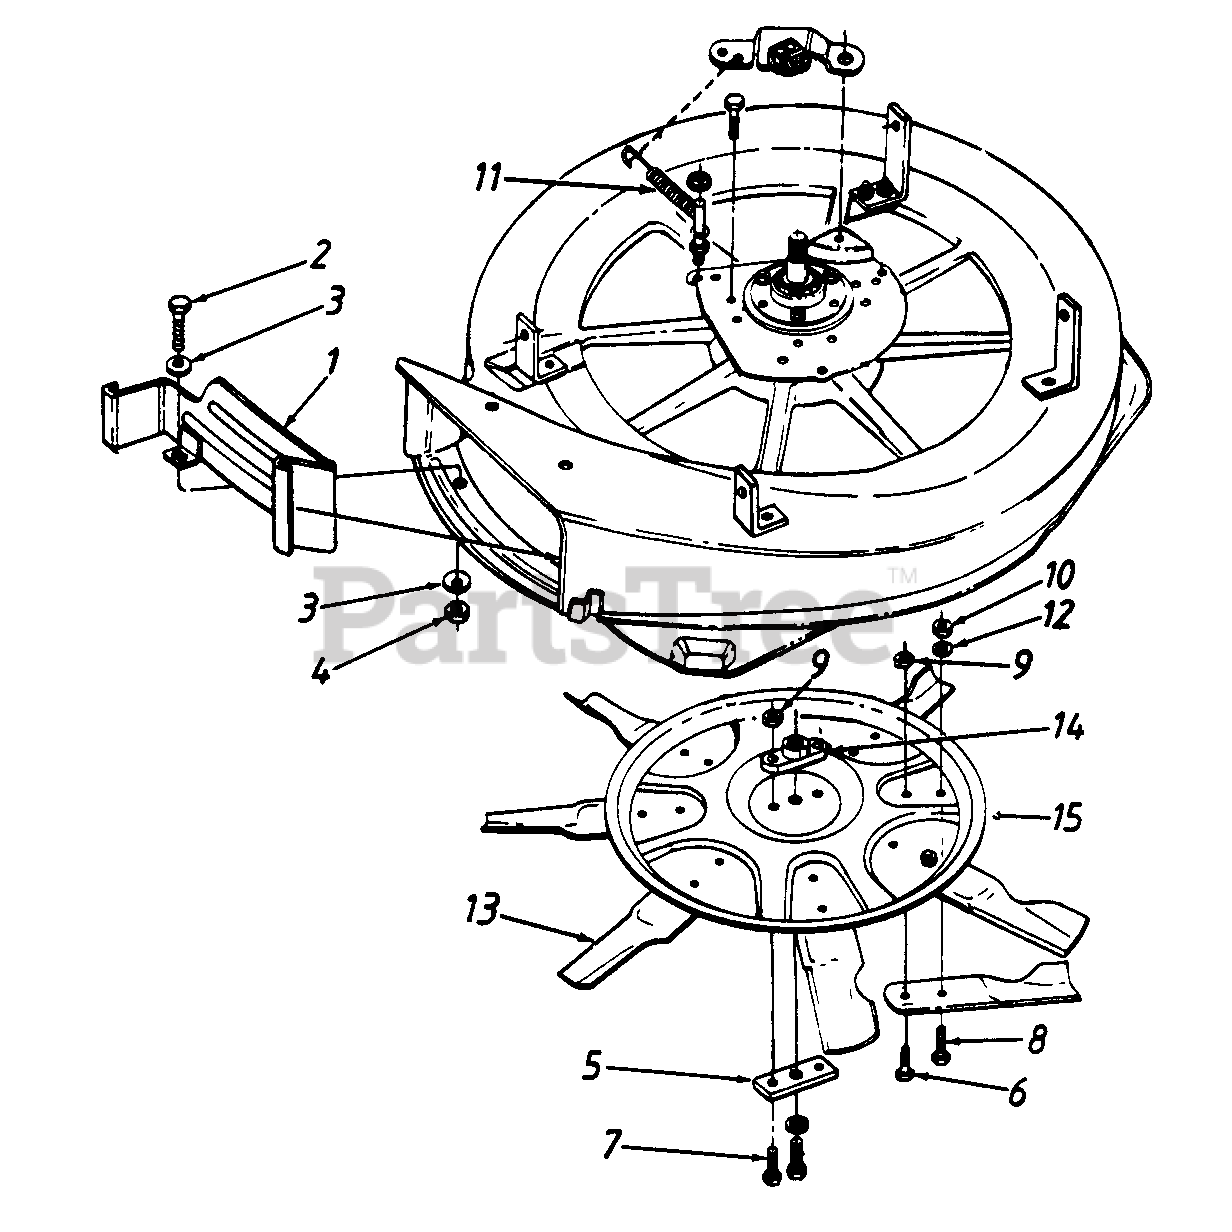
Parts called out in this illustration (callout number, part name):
1	Mulching Baffle Ass'y.
2	Hex Bolt 5/16-18 x .5"
3	Bell-Wash. .325" I.D.
4	Hex L-Nut 5/16-18 Thd.
7	Hex Bolt 5/16-24 x 1.2 5" Lg. (Gr. 5)
8	Hex Bolt 3/8-24 x .88" Lg.
9	Hex L-Nut 5/16-24 Thd.
10	Hex L-Nut 3/8-24 Thd. (Gr. 5)
11	Extension Spring 3.2" Lg.
12	Fl-Wash. .406" I.D. x .75"
13	30" Mulching Blade Tip
14	Blade Adapter
15	30" Mulching Blade Disc
